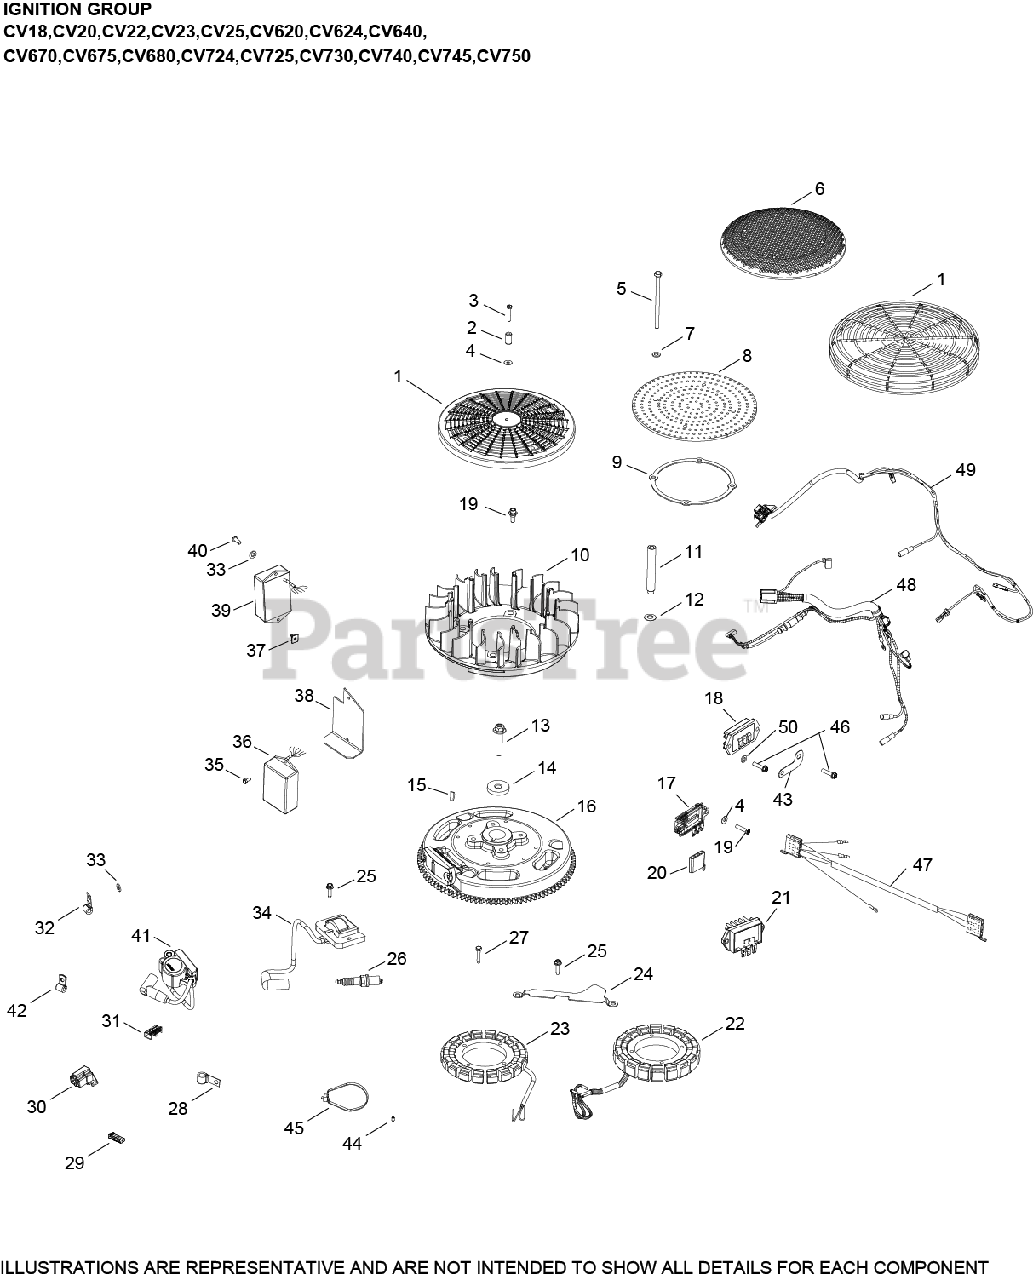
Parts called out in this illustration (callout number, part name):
2	SCREW, CAP M6X1.0X99.5
5	WASHER, FLAT 1/4" (O.D. 5/8")
6	SCREEN, GRASS
7	WASHER, FLAT 1/4" (O.D. 5/8")
9	RING, SUPPORT USE 25 141 08-S
12	WASHER, SPRING 10 MM
13	SCREW, FLG M10X1.5X45 - (#25086361S)
14	WASHER, FLAT 13/32"
15	KEY, 3/16" X 5/8"
18	REGULATOR/RECTIFIER
20	CONNECTOR
23	KIT, 15 / 20 AMP STATOR
25	SCREW, THREAD FORMING - USE 25 086 473-S
26	PLUG, SPARK (PRO SERIES)
27	SCREW, THREAD FORMING
28	CLIP, CABLE
33	WASHER, FLAT 1/4" (O.D. 1/2")
34	KIT, MODULE IGNTN (CDI FIXED)
43	BRACKET, GROUND STRAP USE 24 518 12-S
44	SCREW, SKT SET #10-24X1/4"
46	SCREW, HEX FLANGE HI-LO
48	HARNESS, WIRING
